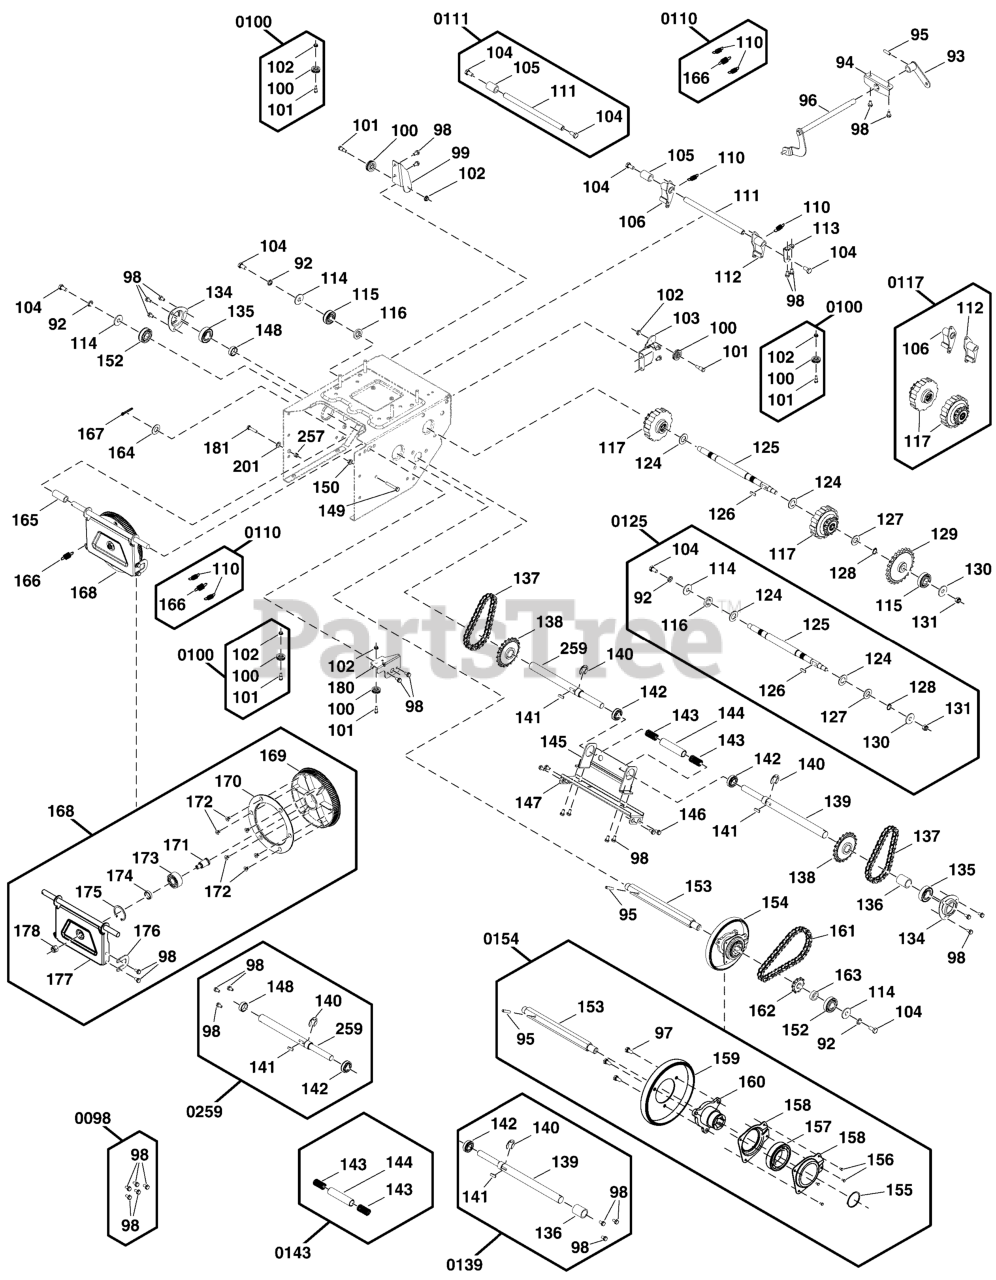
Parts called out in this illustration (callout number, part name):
93	ARM, Speed Select
94	BRACKET, Speed Select
95	PIN, Spring, 6 X 30
96	ROD, Speed Select, Fork
0098	KIT, Hardware
99	BRACKET, Cable Guide, Traction Control
0100	KIT, Pulley, Cable
100	PULLEY, Cable
101	SCREW, M6 X 12, Hex Head Shoulder
103	BRACKET, Cable Guide, Auger Control
105	SLEEVE, PAWL
106	PAWL Assembly, Right
0110	KIT, Spring, Traction Drive
110	SPRING, Pawl
0111	KIT, Shaft, Pawl
111	SHAFT, PAWL
112	PAWL Assembly, Left
113	BRACKET, Pawl
115	BEARING, Ball
116	SPACER, SHAFT, DIFFERENTIAL
0117	KIT, Planitary and Pawl Assembly
117	GEAR, Planitary Assembly
0125	KIT, Shaft, Differential
125	SHAFT, DIFFERENTIAL
129	SPROCKET, 24T
134	RETAINER, Ball Bearing
135	BEARING, Ball
136	SLEEVE, Drive Shaft
137	CHAIN, Roller, 30
138	SPROCKET, 20T
0139	KIT, Shaft, Traction Drive LH
139	AXLE
141	KEY, WOODRUFF
142	BEARING, BALL, DEEP GROOVE
143	SPRING, Drive Shaft
0143	KIT, Spring
144	SLEEVE, Drive Shaft
145	BRACKET, Drive Shaft
147	PLATE, Drive Shaft Bracket
148	SLEEVE, DRIVE SHAFT
152	BEARING, Ball
153	SHAFT, Hex
154	FRICTION WHEEL ASSEMBLY
0154	KIT, Friction Wheel
155	RING, External Retaining
157	BEARING, Ball
158	RETAINER, Ball Bearing
159	WHEEL, Friction
160	HUB, Friction Wheel
161	CHAIN, Roller, 36
162	SPROCKET, 10T
163	BUSHING, Hex Shaft
165	SLEEVE, Spacer, Swinging Plate
166	SPRING, Extension
168	ASSEMBLY, Friction Swinging Plate
169	PULLEY, Friction
170	COVER, Friction Pulley
173	BEARING, Ball
174	SLEEVE, Spacer, Swinging Plate
176	BRACKET, Swinging Plate
177	PLATE, Swinging
180	BRACKET, Cable Guide
201	WASHER, 6x12x.7, Flat
0259	KIT, Shaft, Traction Drive RH
259	AXLE
